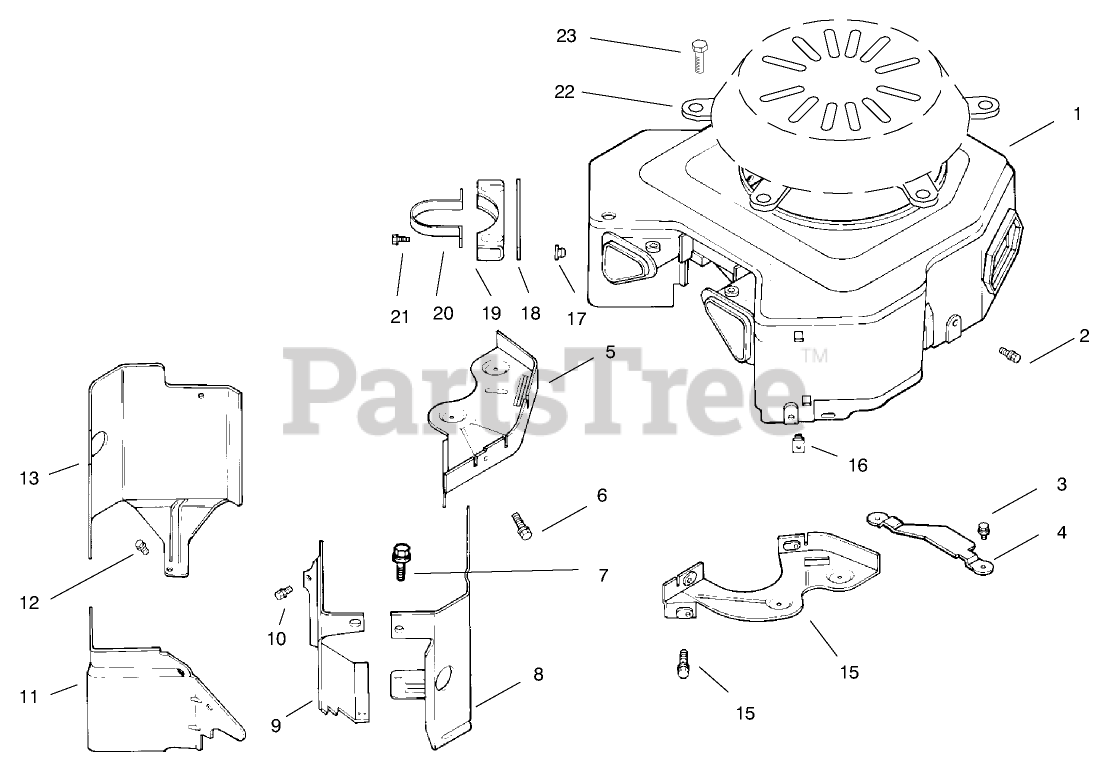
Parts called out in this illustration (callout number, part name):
1	Housing-Blower
2	Screw-HF
3	Screw
4	Guard-Flywheel
5	Plate-Backing #2 Side
7	Screw
8	Baffle-Cylinder, #2
9	Baffle-Valley #1 Side
10	Screw
11	Baffle-Valley #2 Side
12	Screw-HF
13	Baffle-Cyl. #1 Side
14	Screw
15	Plate-Backing #1
16	Nut
17	Nut-Plastic
18	Spacer
19	Bracket
20	Strap-Breather
21	Screw-Hex.
22	Kit-Guard
23	Screw-hex. Flange
